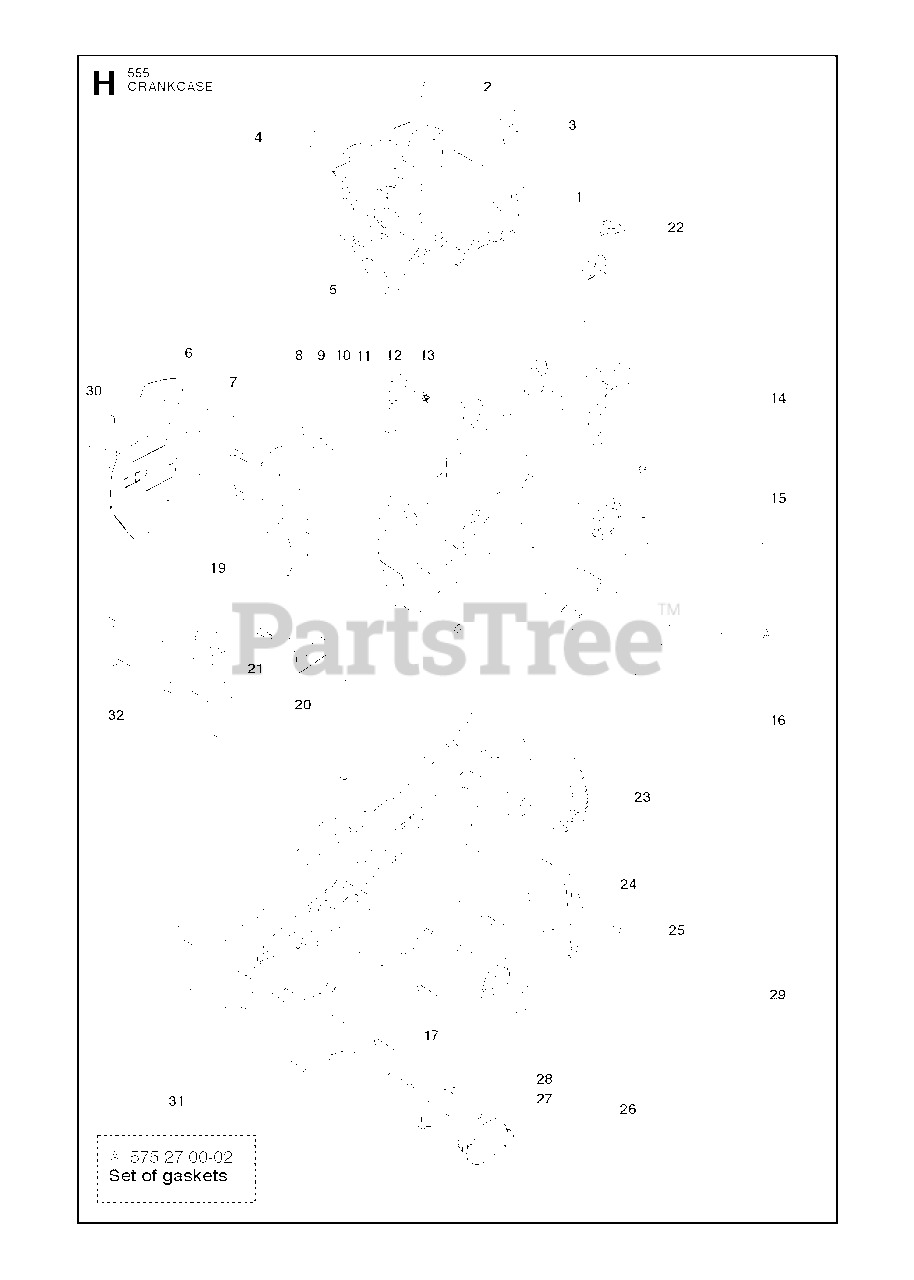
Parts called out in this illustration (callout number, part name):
1	CARBURETTOR AREA BASE
5	RP CRANKCASE ASSY
6	CHAIN GUIDE PLATE
8	PLUG
9	VALVE-CHECK (DUCKBILL)
11	LOCK SPRING
13	PIN
14	SLEEVE
15	BAR BOLT
16	SCREW IHSCM
17	SCREW IHSCM
20	CHAIN CATCHER
22	DEFLECTION LIMITER
23	BUCKLE ORANGE
24	AIR NOZZLE
25	SCREW IHSCM
26	TANK CAP ASSY
27	SEALING
28	HOLDER
29	RADIAL SEAL
30	SCREW CITXPANT
31	GASKET KIT
32	RP ENCLOSED KIT
